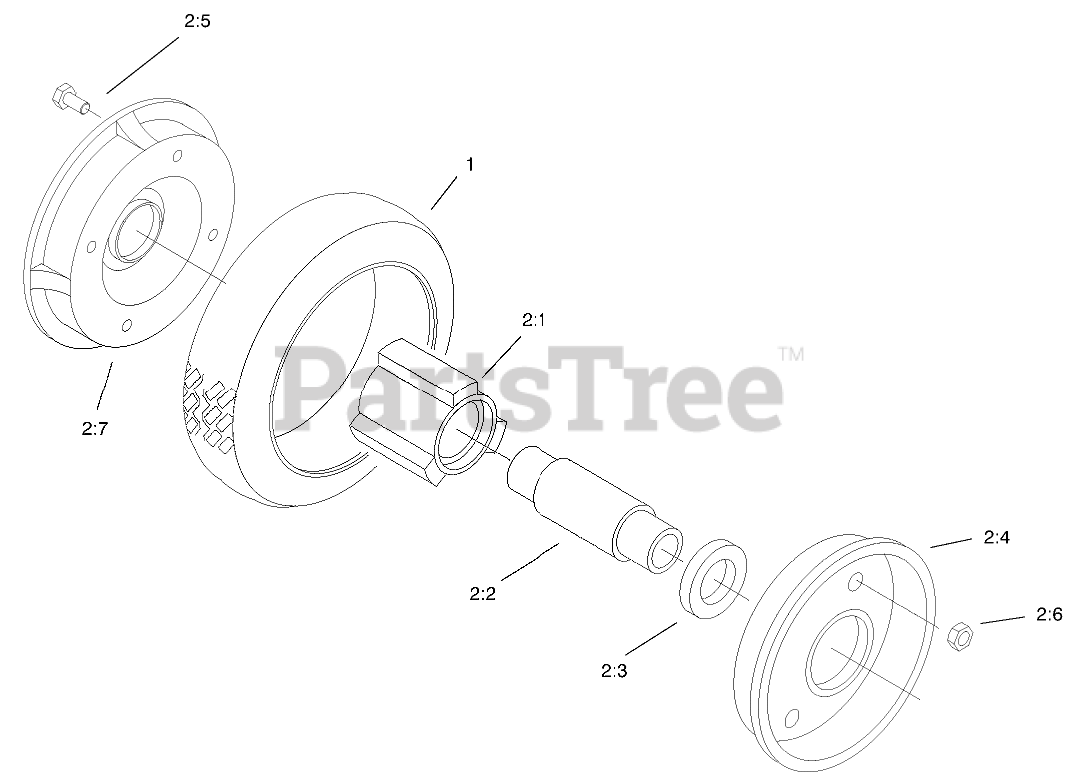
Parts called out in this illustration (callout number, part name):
2	ASM-Wheel and Tire
2:1	HUB-BEARING
2:2	SPACER-BEARING
2:3	BEARING-WHEEL
2:4	Wheel-Half
2:5	SCREW-HH
2:6	NUT-LOCK, NI
2:7	WHEEL HALF AND GEAR ASM
